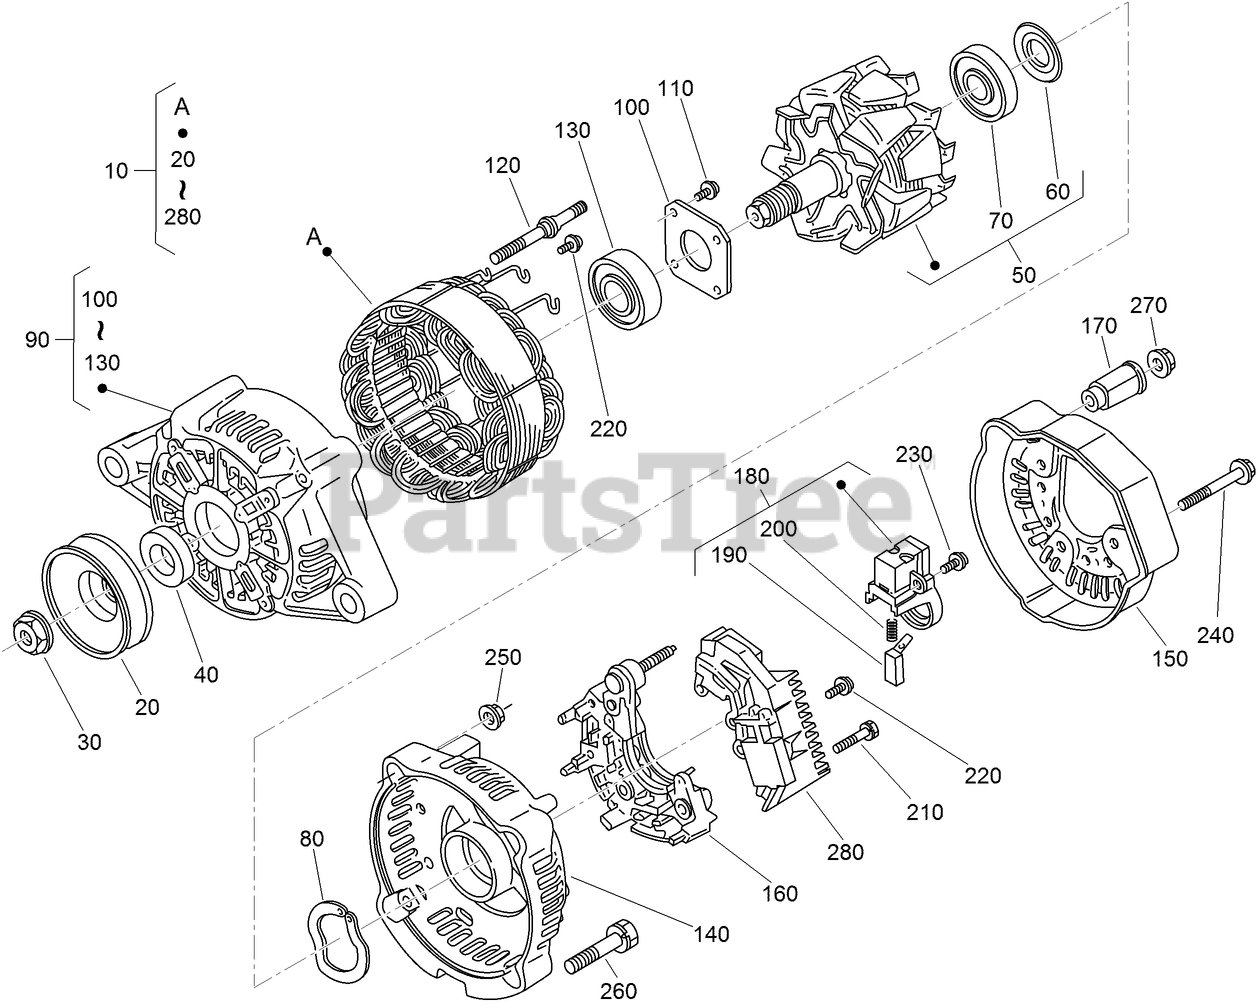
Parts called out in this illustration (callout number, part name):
20	PULLEY-DYNAMO
40	COLLAR
50	ROTOR ASM
60	COVER-BEARING
70	BEARING-BALL
80	WASHER-THRUST
90	DRIVE END FRAME ASM
100	PLATE-RETAINER
110	SCREW-HEAD, ROUND
120	BOLT-THROUGH
140	FRAME-END
150	COVER-END
170	BUSHING-INSULATION
180	BRUSH HOLDER ASM
190	BRUSH
200	SPRING-BRUSH
210	SCREW-HEAD, ROUND
220	SCREW-HEAD, ROUND
230	SCREW-HEAD, ROUND
280	REGULATOR ASM
